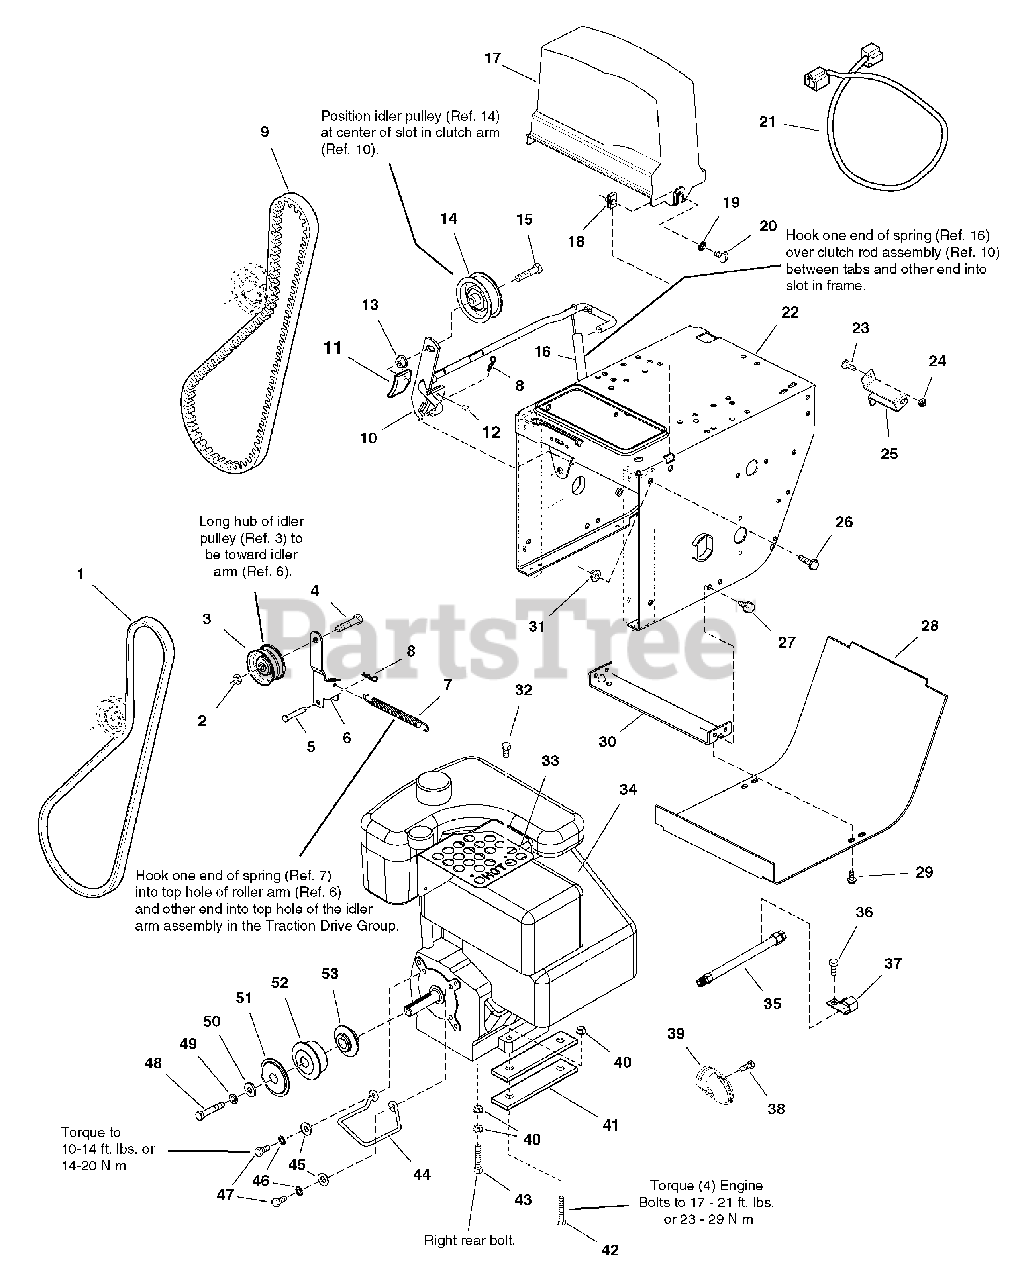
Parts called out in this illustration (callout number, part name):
1	V-BELT, 3L (Used on all models Except 1390 Models)
1	V-BELT, 3L (Used Only on 1390 Models)
2	NUT, Hex, Toplock, Jam, 3/8-16
3	PULLEY, Idler
4	SCREW, Hex Head, 3/8-16 x 1-1/2
5	PIN, Flat Head Drilled
6	ARM, Idler, 5-3/4 LG
7	SPRING, Extension
8	PIN, Quick
9	V-BELT, HA (Used on all models Except 1390 Models)
9	V-BELT, HA (Used Only on 1390 Models)
10	ROD AND ARM ASSEMBLY, Clutch, Brake w/Pad
13	NUT, Hex Flange, 3/8-16 Whiz Lock Large
14	PULLEY, Idler
15	SCREW, Hex Whiz Lock Flange, 3/8-16 x 1-3/4
16	SPRING, Extension
17	COVER, Belt
18	NUT, Speed, 5/16-18, Lug Type
19	LOCKWASHER, External Tooth, 5/16
20	SCREW, Truss head Slotted, 5/16-18 x 3/4
21	CORD, Electric Extension
22	FRAME ASSEMBLY, Chain/Tube Handles
23	CARRIAGE BOLT, 1/4-20 x 3/4 G5
24	NUT, Hex KEPS, 1/4-20, Conical Washer
25	SUPPORT, Clutch Cable, 16GA
26	SCREW, Hex Whiz Lock Flange, 5/16-18 x 3/4
27	SCREW, Hex Washer Head Taptite, 5/16-18 x 3/4
28	COVER, Bottom Frame, 20GA
29	SCREW, Hex Washer Head Taptite, 1/4-20 x 1/2
30	SUPPORT, Tie Bar
31	NUT, Hex Flange, 5/16-18, Whiz Lock Large
32	GUARD, Muffler, 18GA
33	SCREW, Hex Washer Head Taptite, #10-24 x 1/2
34	ENGINE, 9.5HP Briggs & Stratton Electric Start
35	HOSE, Oil Drain, w/Fittings
36	CAPSCREW, Hex Washer Head, 5/16-18 x 3/4
38	SCREW, Muffler Deflector
39	DEFLECTOR, Rain Guard, B&S Snow Muffler
40	NUT, Hex Flange, 5/16-18, Whiz Lock Small (Quantity 4 used only on 9560 Models)
41	SUPPORT, Engine Riser (Used on all models Except 1390 Models)
42	CAPSCREW, Hex Whiz Lock Flange, 5/16-18 x 2-1/4 (Used on all models Except 1390 Models)
42	CAPSCREW, Hex Head, 5/16-18 x 1-1/2 G5 (Used only on 1390 Models)
43	CAPSCREW, Hex Washer Head Taptite, 5/16-18 x 2-1/2 (Used on all models Except 1390 Models)
43	CAPSCREW, Hex Head 5/16-18 x 1-3/4 G5 (Used only on 1390 Models)
44	STOP, Belt
45	WASHER, 5/16
46	LOCKWASHER, Spring, 5/16
47	CAPSCREW, Hex Head, 5/16-24 x 3/4 G5
48	CAPSCREW, Hex Head, 3/8-24 x 1-1/2 G8
49	LOCKWASHER, Spring, 3/8
50	WASHER, 3/8
51	PULLEY, Engine Outside, Powdered Metal
52	PULLEY, Engine Middle, Powdered Metal
53	PULLEY, Half Powdered Metal
